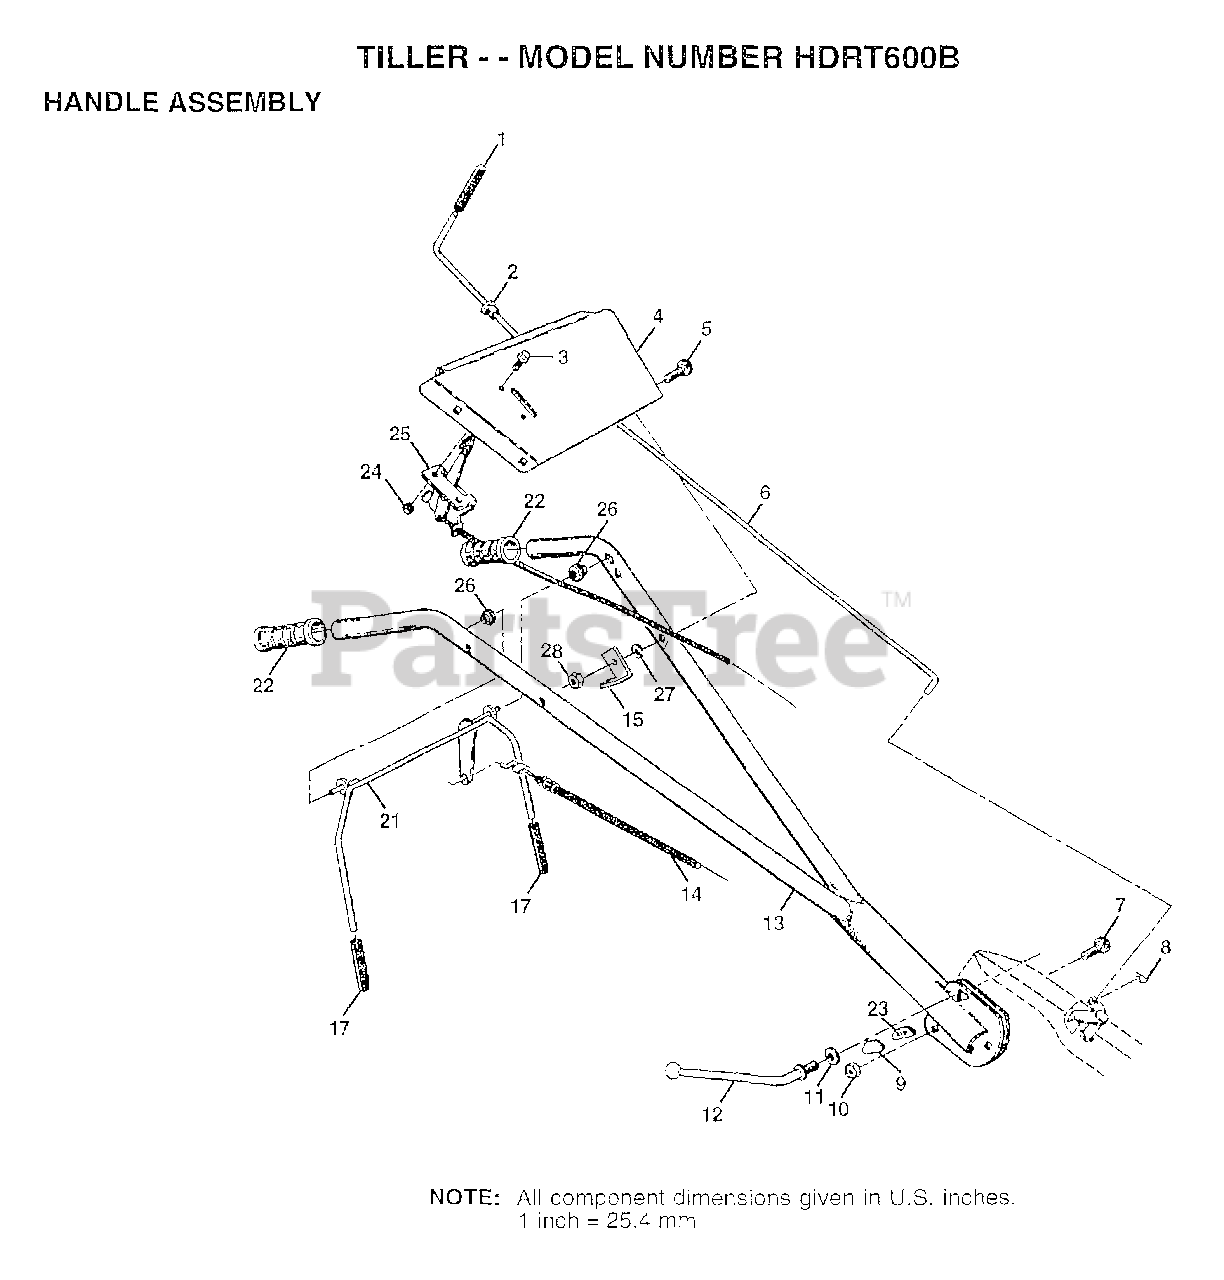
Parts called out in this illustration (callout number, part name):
1	GRIP TI
2	BUSHING
3	SCREW.PNHD.10-24
4	BRACKET.HDLE.TILL
5	BOLT CARRIAGE CRT
6	ROD SHIFT CRT
7	BOLT D
8	RETAINER M
9	LOCK CRT
10	LOCKNUT
11	WASHER CRT
12	LEVER LOCK CRT
13	HANDLE.ASM.V-PLOW
14	CABLE.CLUTCH.Z-BE
15	BRACKET.CLUTCH.CA
17	GRIP BAR CRT
18	SHOULDER BOLT ST
19	LOCKWASHER
21	BAR.ASM.CNTRL.VPL
22	GRIP HDLE NUBBED
23	LOCK.HANDLE
25	CONTROL.TRTL.6HP.
26	GROMMET.HANDLE.V-
27	LOCKWASHER
28	NUT
